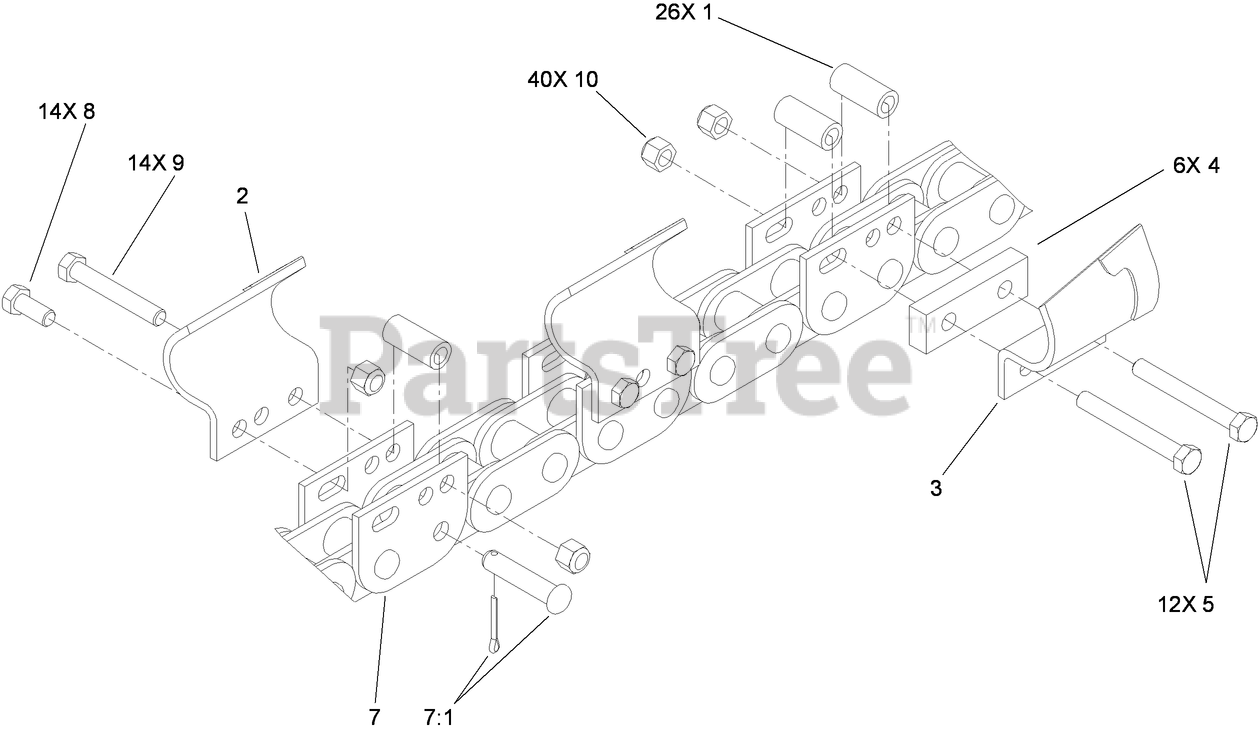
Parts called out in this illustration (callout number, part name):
1	SPACER-TUBE
2	TOOTH-SOIL, LH
3	TOOTH-SOIL, RH
4	SPACER-CUT, 5 INCH
5	SCREW-HH
7	CHAIN-BARE, 40 STATION
7:1	PIN-CONNECTING,
8	SCREW-HH
9	SCREW-HH
10	NUT-LOCK
